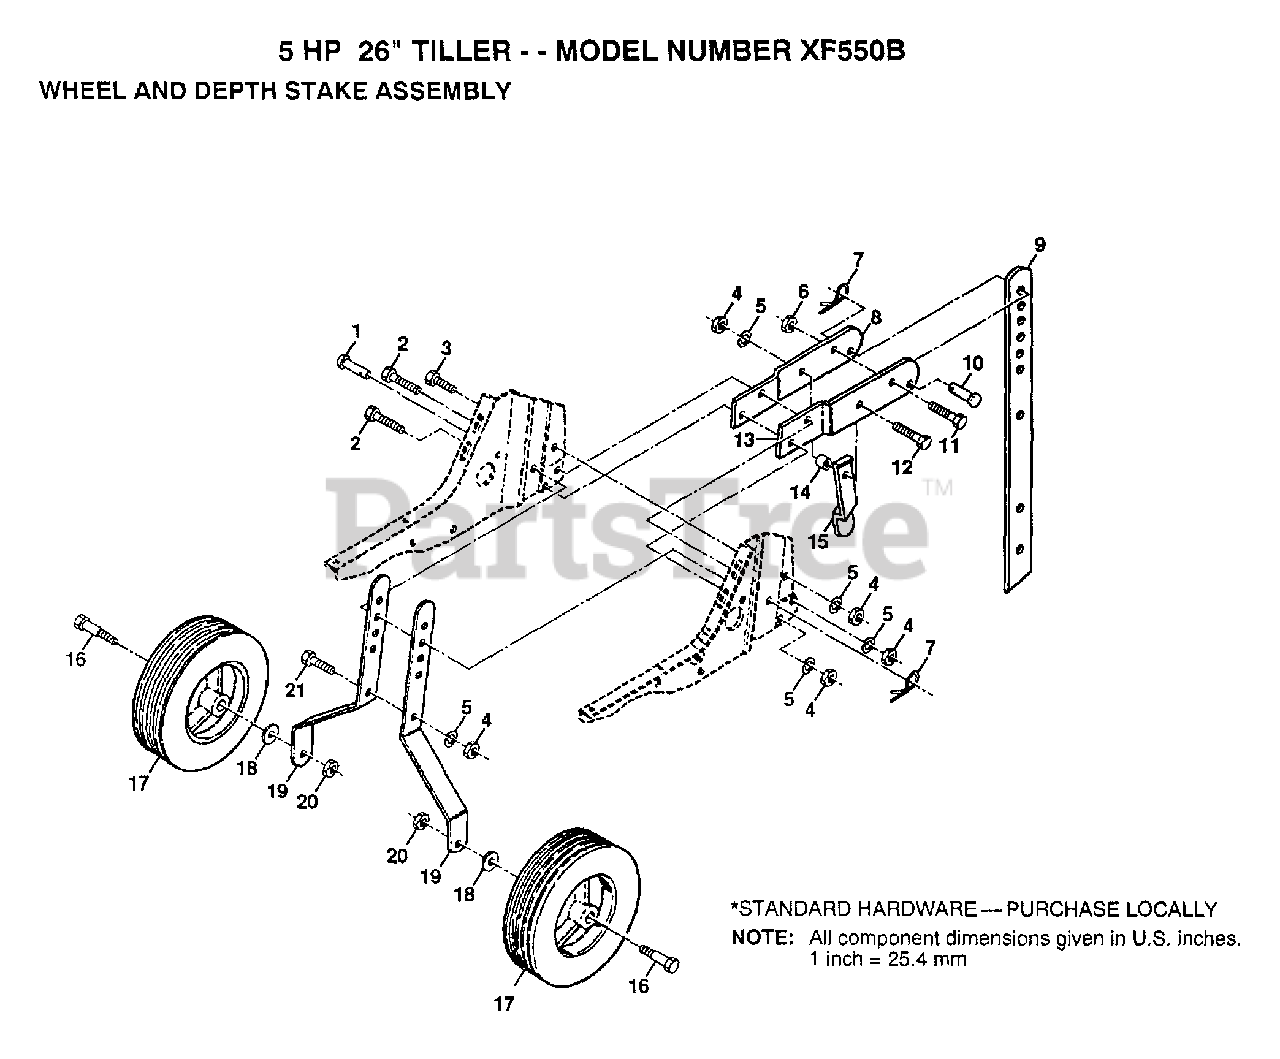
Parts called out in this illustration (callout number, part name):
1	DRILLED RIVET RT
3	BOLT
4	NUT.HEX.5/16-18
5	LOCKWASHER
6	GRIPCO NUT
7	SPRING.RETAINER
11	BOLT.3/8-24X1-1/2
12	BOLT.HEX.5/16-1.5
14	WASHER
15	STAKE SPRING TI
16	BOLT SHOULDER
18	WASHER
